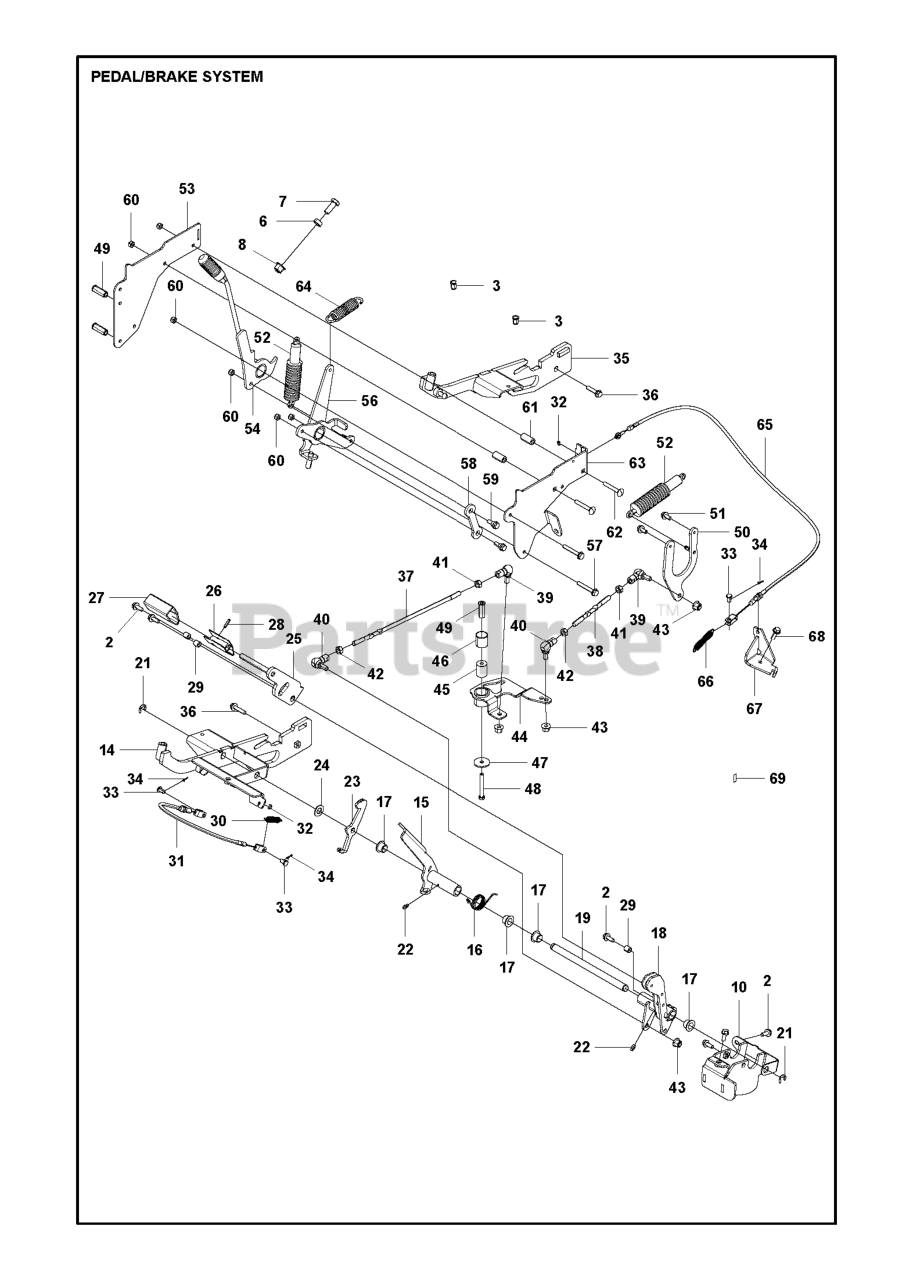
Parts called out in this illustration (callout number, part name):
1	TRANSMISSION ASSY
2	GEARCASE LH W/BRG
3	GASKET TI
4	NEEDLE BRNG LT
5	THRUST WASHER
6	GEAR.PINION.INPUT
7	SHAFT.INPUT."D".TILLER
8	BEARING TI
9	WASHER, SEAL (2 2)
10	STEEL BALL KIT
11	SPRING-SHIFT CRT
13	BRACKET ASM.SHIFT.CRT
14	SHIFT FORK TI
16	SHAFT.SHIFTER.TILLER
20	GEAR ASSY CRT
21	GEAR-REV IDLR CRT
22	NEEDLE BEARING TI
24	LOCKWASHER
25	NUT.ASF.HEX.7/16
27	BEARING, SHAFT LH CRT
30	GROUND SHAFT ASS'Y
31	BEARING, SHAFT RH CRT
33	SPRCKT 8 GEAR CRT
34	SHAFT.SECONDARY.REDUCTION.CRT
35	SCRW WHIZ LOK CRT
36	SPROCKET.ASM.W/BEARING.TILLER
37	BEARING
38	SPROCKET, TINE
41	SHAFT.REDUCTION.TILLER
42	BRNG RACE T
44	SEAL ASM, OIL
48	GEARCASE RH W/BRG
49	TINE SHAFT
50	CHAIN.TILLER
51	SCREW
53	BEARING KIT
